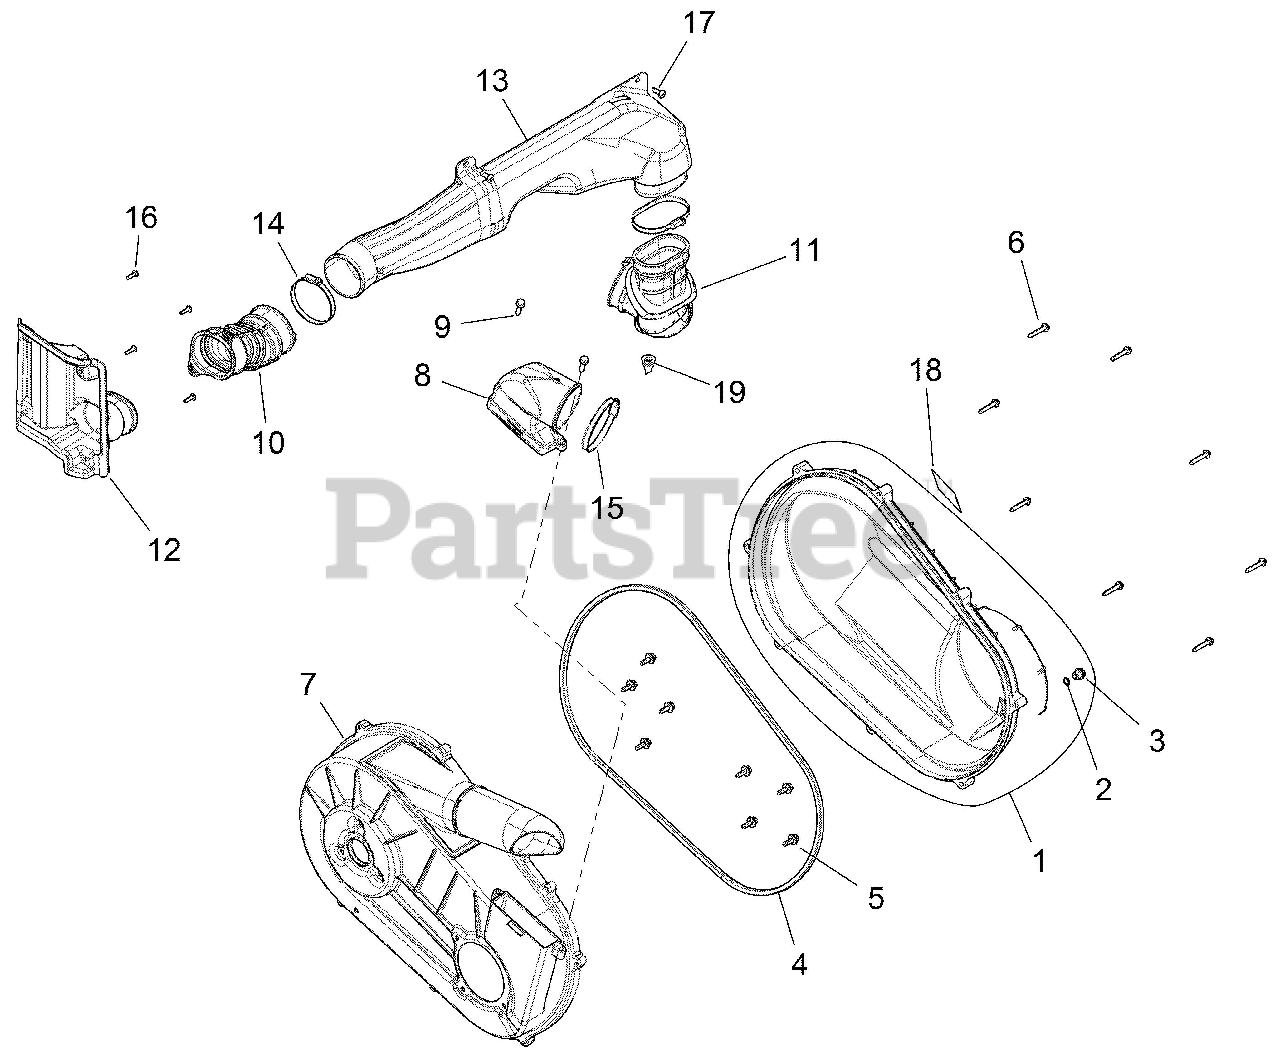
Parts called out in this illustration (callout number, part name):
1	ASM-COVER,CLUTCH,OUTER
2	O RING-.364X.504X.07
3	PLUG-DRAIN
4	SEAL-OUTER CLUTCH COVER
5	ASM-BOLT/WASHER,20 MM
6	SCR-HXFL-M6X35 ZOD HILO
7	ASM-COVER,CLUTCH,INNER
8	DUCT-CLUTCH,AIR IN
9	SCREW (10)
10	HOSE-INTAKE,CLUTCH
11	HOSE-CLUTCH,AIR IN,TRAP,570
12	INTAKE-FENDER-REAR
13	DUCT-INTAKE,CLUTCH
14	CLAMP,BAND,NARROW (10)
15	CLAMP-BAND,NARROW 70-90MM
16	SCR-10X5/8-HI/LO,PN-T25,TRX-M
17	SCR-TX TRUSS-#14X3/4,HI/LO ZBK
18	DECAL, BELT, CAUTION/CHECK
19	PLUG-DRAIN
